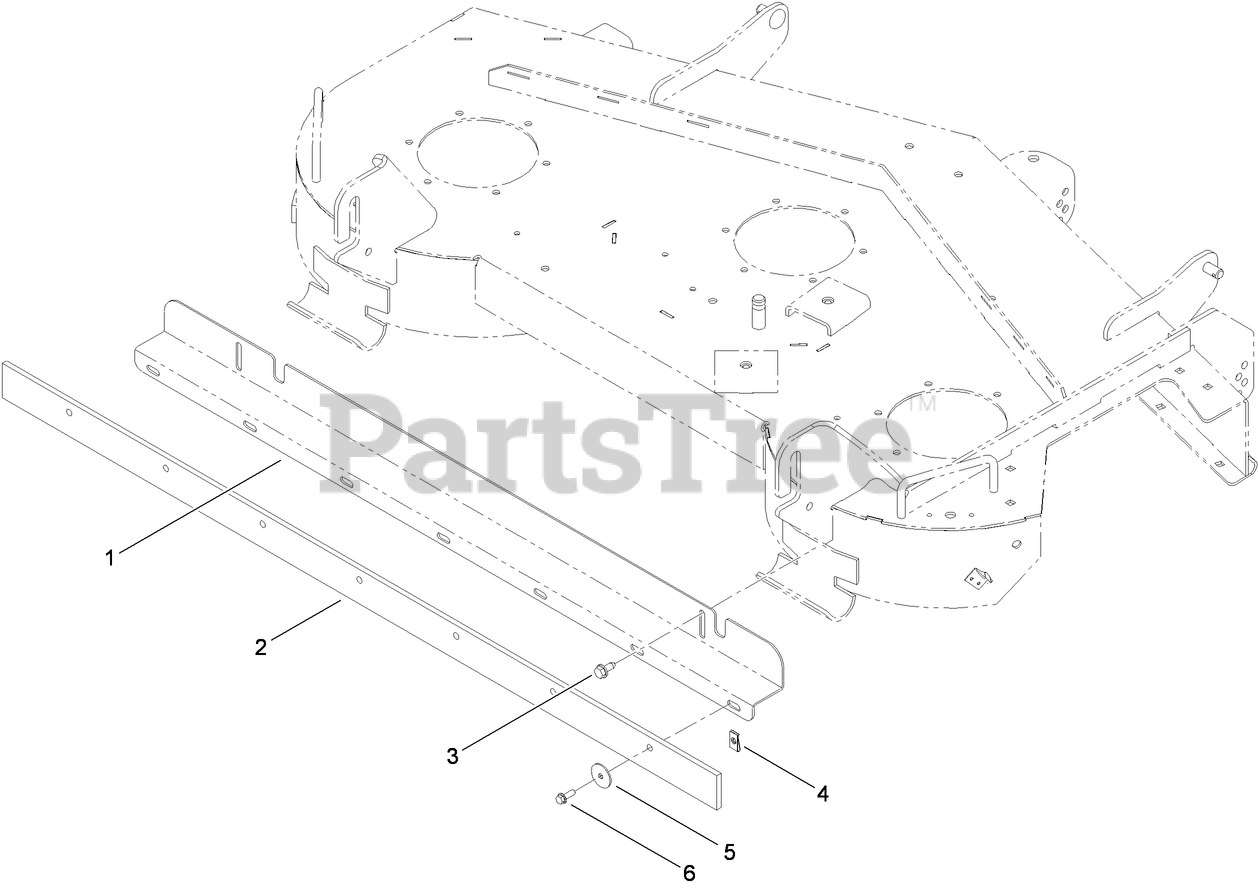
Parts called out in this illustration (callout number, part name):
1	BRACKET-STRIPING
3	SCREW-HWHTF
4	NUT-SPEED
5	WASHER-FLAT
6	SCREW-HHF
